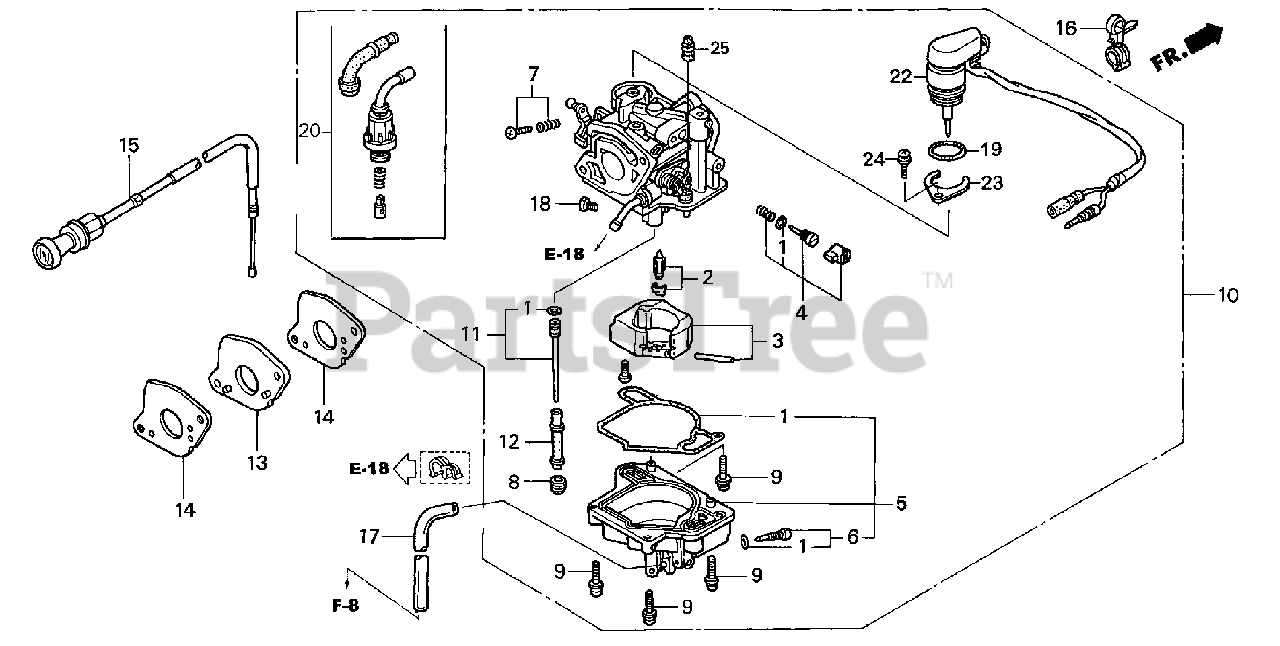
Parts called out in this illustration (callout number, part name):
1	GASKET SET
2	VALVE SET, FLOAT
5	CHAMBER SET, FLOAT
6	SCREW SET, DRAIN
8	SCREW, PLUG
9	SCREW-WASHER
10	CARBURETOR ASSY. (BJ02B A)
10	CARBURETOR ASSY. (BJ02B D)
11	JET SET (#45)
12	NOZZLE, MAIN
13	INSULATOR, CARBURETOR
14	GASKET, CARBURETOR
16	CLIP, TUBE (135MM)
17	BULK HOSE, VINYL (4X7X8000) (4X7X200)
18	JET, MAIN (#100)
18	JET, MAIN (#102)
18	JET, MAIN (#105)
19	O-RING, BYSTARTER
21	SCREW, PAN
22	BYSTARTER ASSY., AUTO
24	SCREW-WASHER
